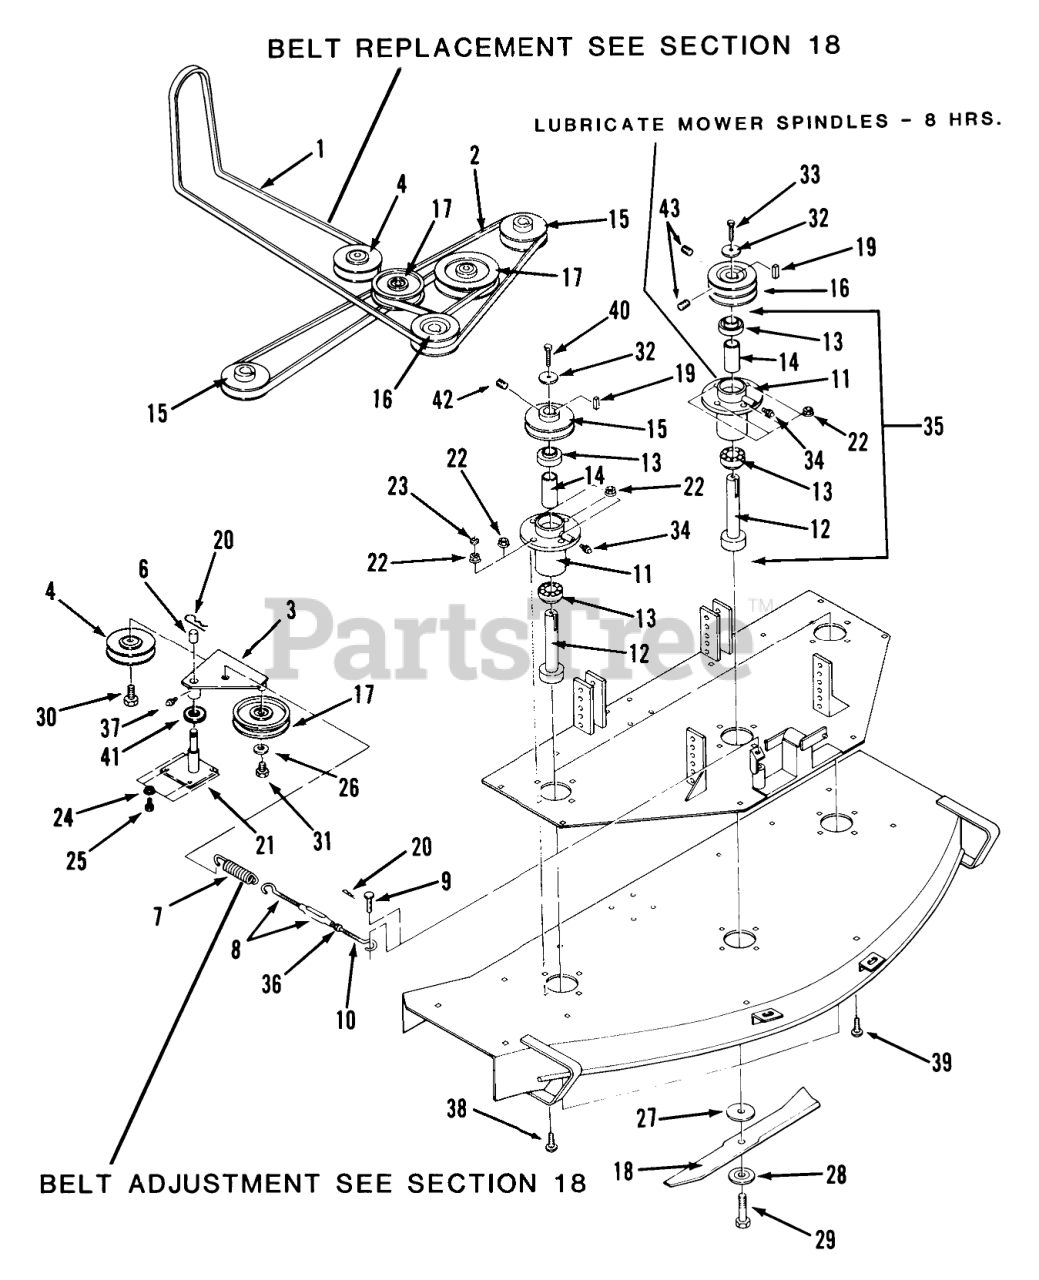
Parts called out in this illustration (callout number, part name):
1	V-BELT
1	BELT-60" MOWER DRIVE
2	Mower Spindle Belt (105.5")
2	BELT-V
3	Belt Tensioning Swing Arm
4	PULLEY-V IDLER
6	Bronze Bushing
7	SPRING-EXTENSION
8	TURNBUCKLE
9	Idler Spring Pin
10	EYEBOLT B-150-K
11	Mower Hub
12	SHAFT MOWER SPINDLE
13	Mower Bearing
14	Spacer
15	Sheave-1 Groove
15	PULLEY-SGL 30220-Z60
16	PULLEY 2-GROOVE
16	PULLEY-SHE 30221-Z60
17	Flat Idler
18	Mower Blade 17"
18	BLADE
20	Hairpin
21	BELT-TENS 30235-Z87
22	NUT
23	NUT
24	Nut 1/4-20
25	Bolt
26	Lockwasher
27	WASHER FIBER
28	WASHER CUPPED
29	BOLT HEX 5/8-18X21/2
30	Hex Bolt 5/8-11 x 1
31	Bolt
32	Cupped Washer
33	Bolt 3/8-24 x -1/4
34	ZERK 90DEGREE
35	Spindle Assembly (Includes items 11, 12, 13 & 34)
36	Nut
37	Zerk
38	Bolt
39	Bolt
40	HEX HD CAP SCREW
41	SPACER-PIVOT 30112
42	Set Screw
43	SCREW-SET
